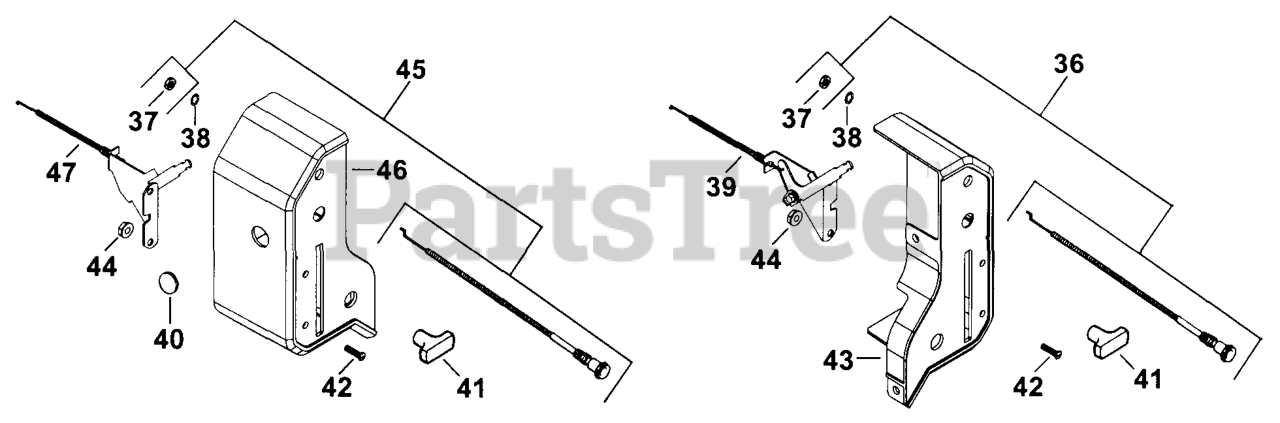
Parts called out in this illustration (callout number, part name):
37	NUT, 3/8-24 GRADE 2 USE 25 100 25-S
38	WASHER, INT TOOTH LOCK 3/8"
40	PLUG, BUTTON
41	KNOB, PRESS-ON
42	SCREW, PHL PAN HD M5X0.8X10
44	NUT, LOCK M5X.8
45	KIT,CHOKE W/NUT CABLE ASSY - DISCONTINUED
46	HOUSING, CONTROL PANEL
47	CABLE, THROTTLE - DISCONTINUED
